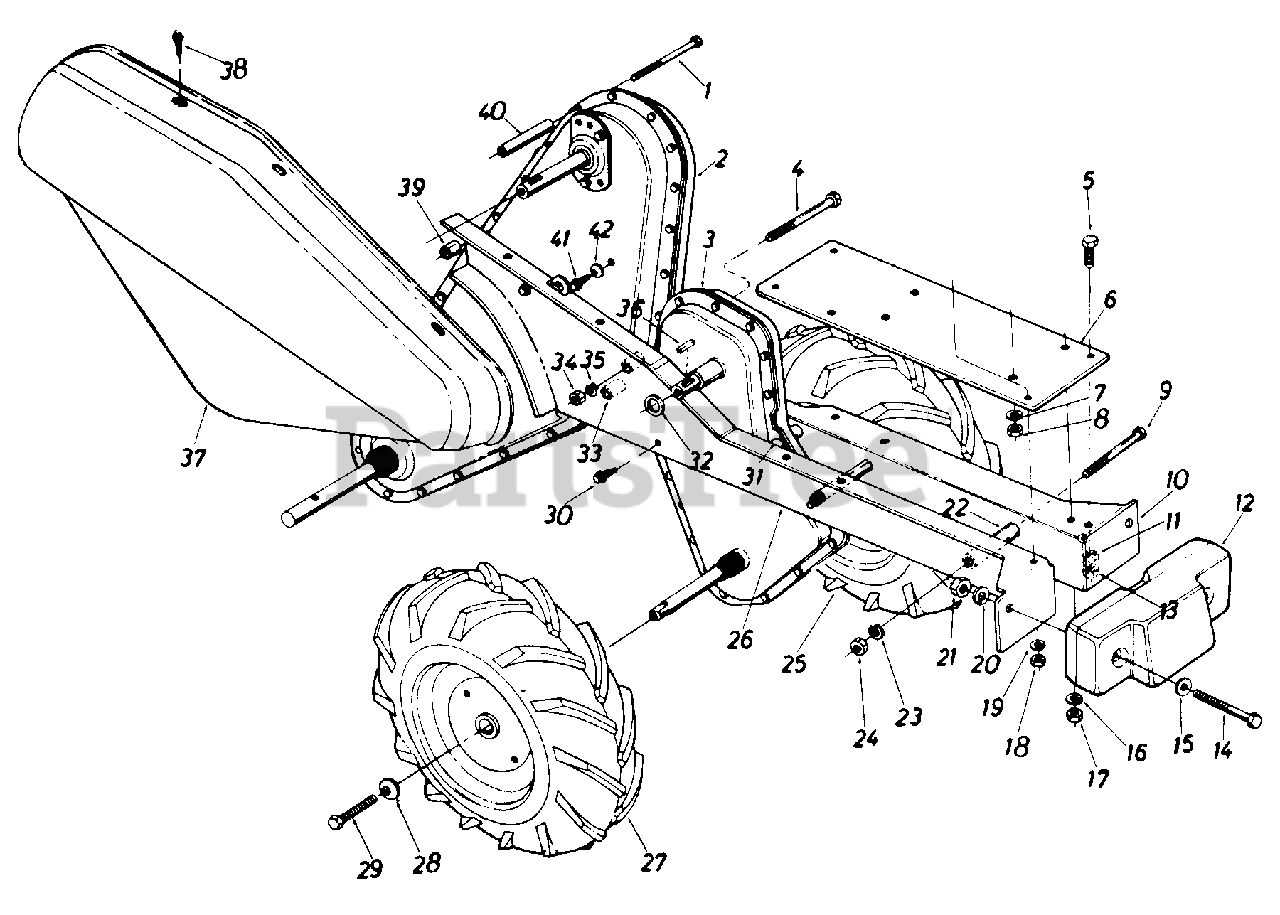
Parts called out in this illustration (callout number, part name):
1	Hex Bolt 5/16-18 x 3.00" Lg.*
2	Chai n Case Ass'y. Comp. Tines
3	Chain Case Ass'y. Comp. Wheels
4	Hex Bolt 5/16-18 x 3.00" Lg.*
5	Hex Bolt 5/16-18 x .75" Lg.*
8	Hex Nut 5/16-18 Thd.*
9	Hex Bolt 3/8-24 x 3.00" Lg.*
13	Hex Nut 5/16-18 Thd.*
14	Hex Bolt 1/2-13 x 4.00" Lg.*
15	Fl-Wash. .510" I.D. x 1.0" O.D.
16	L-Wash. 5/16" I.D.*
17	Hex Nut 5/16-18 Thd.*
18	Hex Nut 5/16-18 Thd.*
19	L-Wash. 5/16" I.D.*
20	L-Wash. 1/2" I.D.*
21	Hex Nut 1/2-13 Thd.*
22	Spacer .38" I.D. x .62" O.D. x 2. 1 8 " Lg.
23	L-Wash. 3/8" I.D.*
24	Hex Nut 3/8-24 Thd.*
25	Wheel Ass'y. Comp. 12.5 x 3.5 L. H .
28	Belleville Wash. .345" I.D. x .88" O.D.
29	Hex Bolt 5/16-24 x .62" Lg.*
30	Hex Wash. Hd. SF-Tap Scr. 5/16-24 x .50" Lg.
31	Spacer .326" I.D. x .47" O.D. x .96" Lg.
32	Fl-Wash. .635" I.D. x 1.00" O.D.
33	Spacer.326" I.D. x .47" O.D. x .96 " Lg. .
34	Hex Nut 5/16-18 Thd.*
35	L-Wash. 5/16" I.D.*
36	Sq. Key 3/16 x .75" Lg.
37	Belt Cover
38	Hex Wash. Hd. SF-Tap Scr. 1/4-20 x .50" Lg.
39	Spacer .326" I.D. x .47" O.D. x .96" Lg.
40	Spacer.375" I.D. x .500" O.D. x 2.00" Lg.
41	Hex Wash. Hd. SF-Tap Scr. 1/4-20 x .50" Lg.
42	Bell-Wash. .265" I.D. x .75" O.D.
